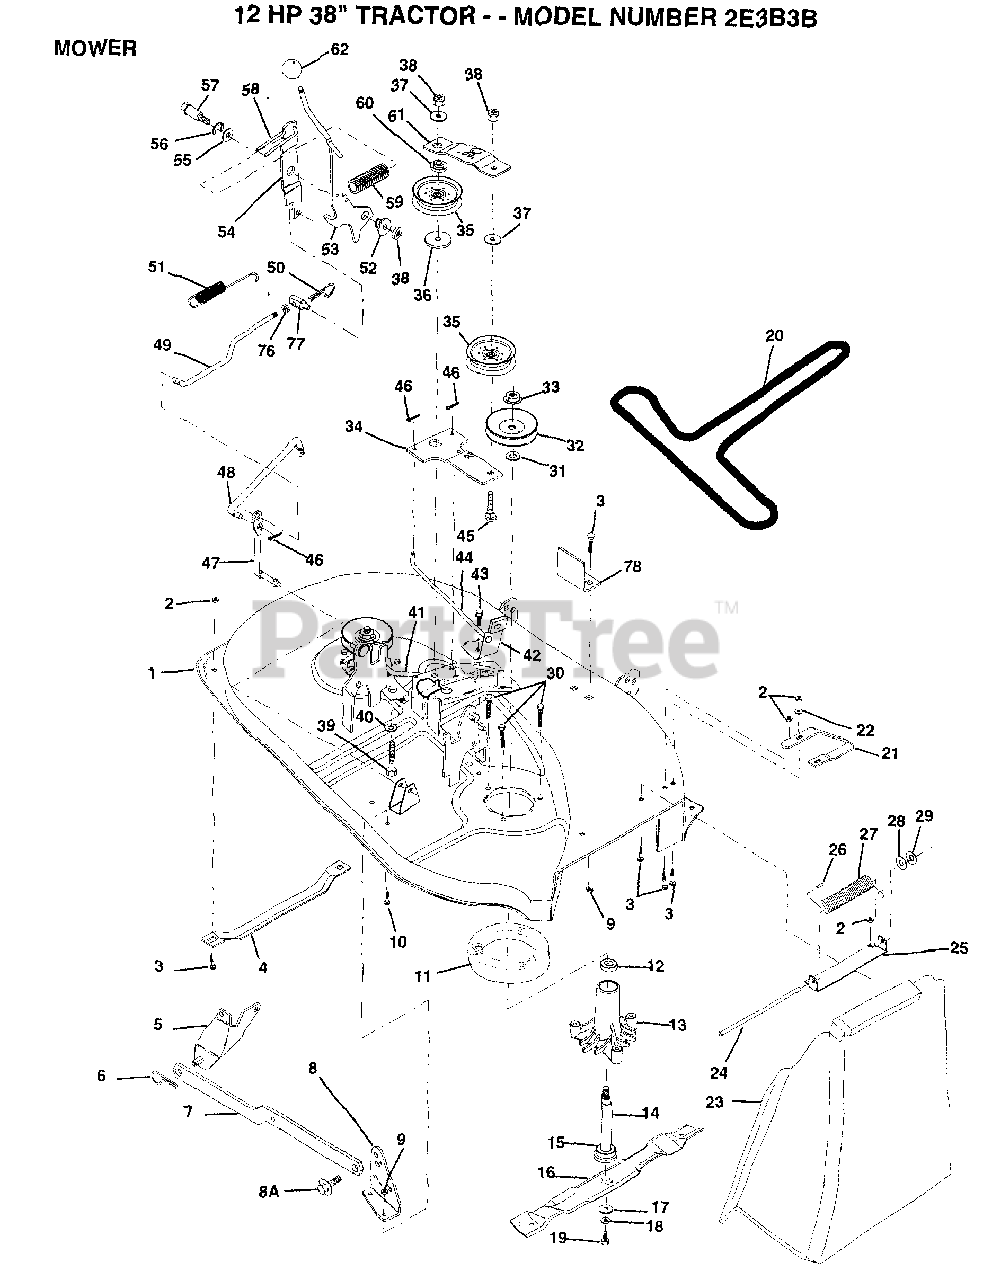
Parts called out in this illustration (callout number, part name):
2	NUT
3	BOLT
4	RUNNER-LH M
5	BRKT ASM SWAY BAR
8	BRKT DECK SW BAR
8A	BOLT SHD 5/16-18
9	NUT
10	BOLT
12	BEARING
13	HSG ASM MANDREL
15	BEARING.BALL
16	"BLADE.38""V.MULCH"
17	WASHER.HARD.BLADE
19	BLADE BOLT
20	V BELT
21	RUNNER RH
22	WASHER M
23	DEFLECTOR-SHLD T
24	ROD-HINGE T
25	BRKT DEFLECTOR
26	CAP-SLEEVE LT
27	SPRING TORSION
28	WASHER
29	NUT PUSH M
31	WASHER
34	IDLER ARM ASSY
35	FLAT IDLER PULLEY
36	SPACER RETAINER
37	WASHER GT
39	BOLT
40	WASHER GT
41	BRAKE ROD LH
42	BRAKE ASM
43	SCREW
44	BRAKE ROD RH
45	BOLT
47	PIVOT ROD
48	CLUTCH ROD SECOND
49	ROD CLUTCH 38/42
50	RETAINER M
51	RETURN SPRING
52	BUSHING
54	CLUTCH ARM SECOND
55	WASHER
56	RING
57	SHOULDER BOLT
58	SPRING KEEPER
60	RETAINER SPACER
61	IDLER ARM STIFF
62	KNOB T(3/8 HOLE)
76	NUT
77	TRUNION ADJ
78	UPSTOP DECK FT 38
